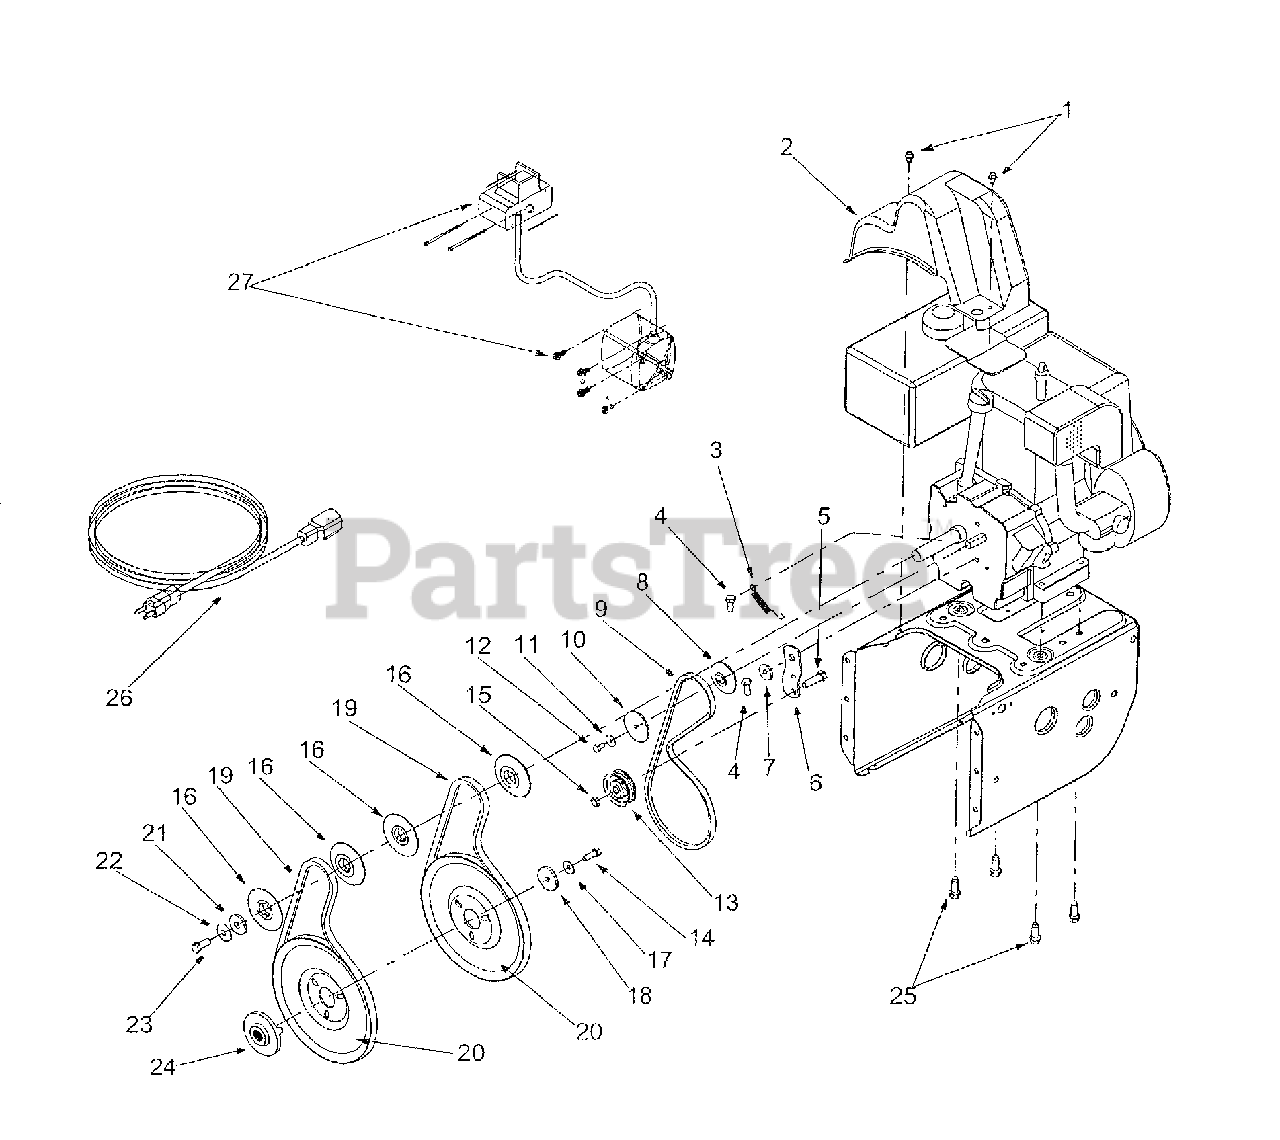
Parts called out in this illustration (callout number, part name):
1	Hex Washer Screw 1/4-20 x .625
2	Belt Cover
3	Extension Spring
4	Hex Screw 5/16-24 x .75
5	Hex Cap Screw 3/8-16 x 1.25
8	Pulley Half
9	V-Belt
10	Pulley Half
11	Bell Washer
12	Hex Cap Screw 1/4-28 x .50
13	Flat Idler
14	Lock Hex Cap Screw 5/16-24
15	Lock Jam Nut 3/8-16
16	Pulley Half
17	Bell Washer
18	Flat Washer
19	Belt
20	Auger Pulley
21	Flat Washer 3/8 x 1.25 OD
22	Bell Washer
23	Hex Cap Screw 3/8-24
24	Adapter Pulley
25	Hex Screw 3/8-16 x 1.0
26	Extension Cord
27	Electric Start
